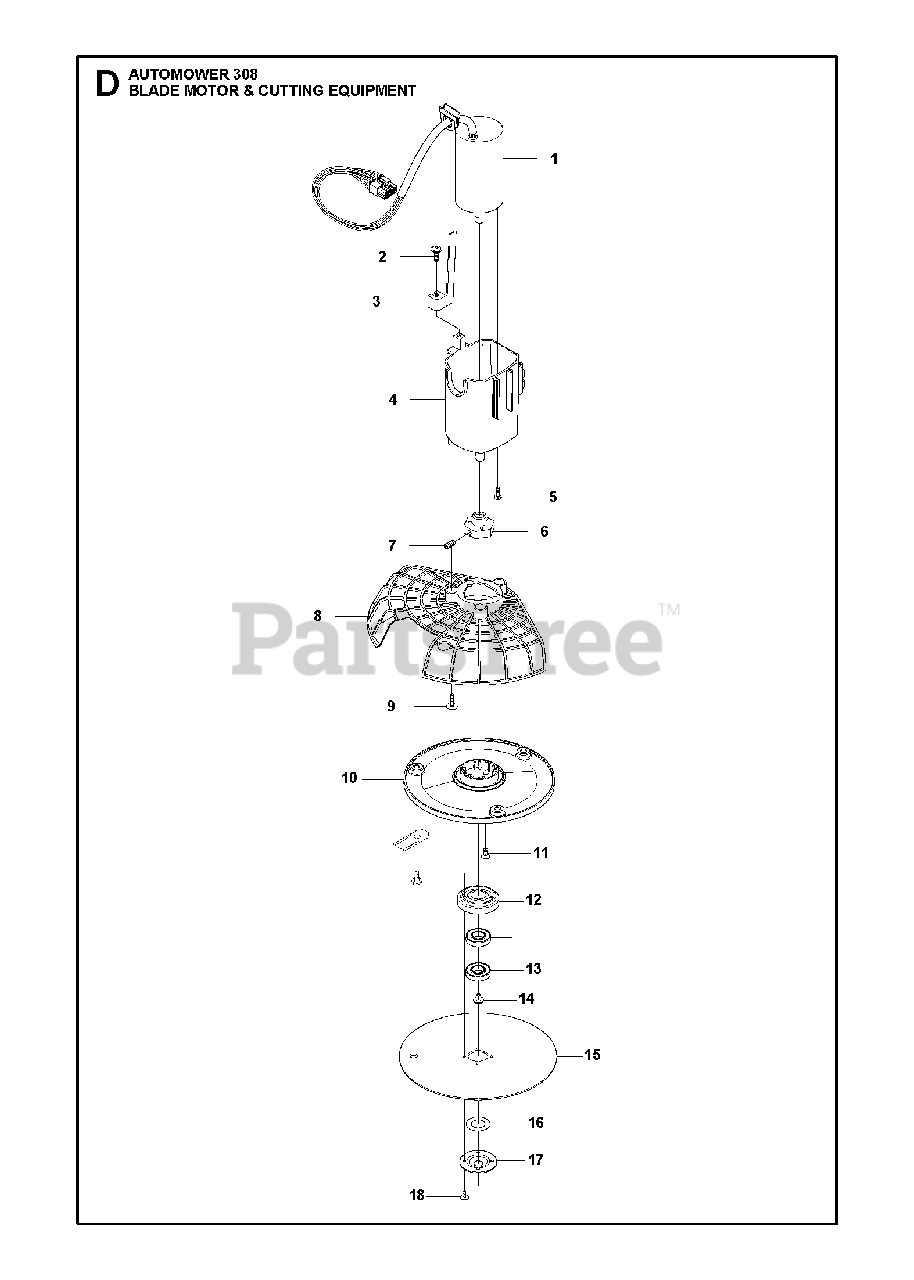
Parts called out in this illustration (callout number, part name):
2	SCREW 14MM
3	HEIGHT INDICATOR
5	SCREW ITXPANM M4X12 8
7	SCREW IHSETM M5X10 8.
9	SCREW 14MM
11	SCREW
17	COVER SKID PLATE
18	SCREW SILVER 10MM
